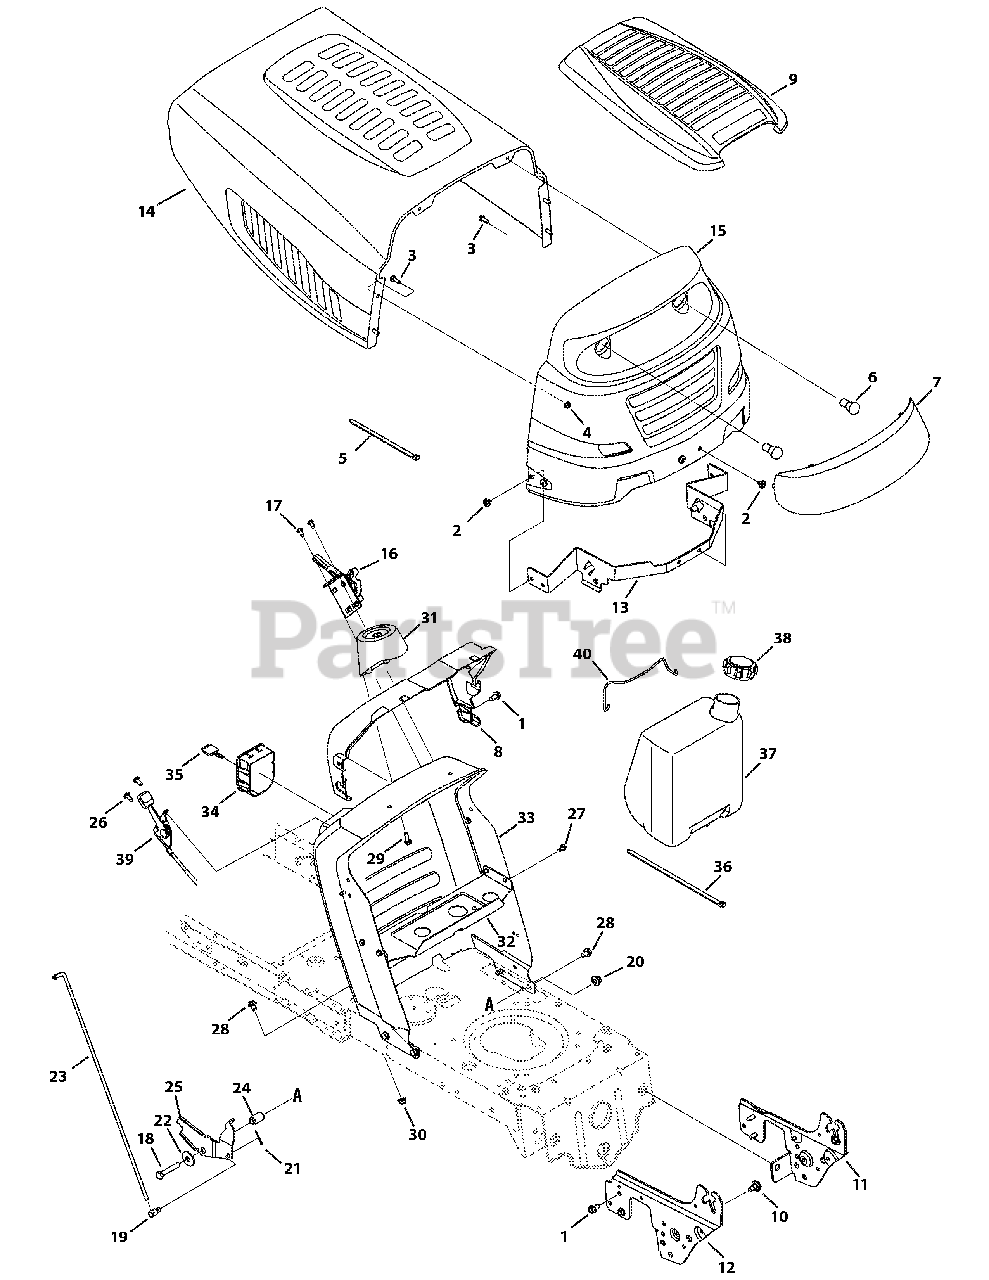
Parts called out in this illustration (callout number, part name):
1	Screw 5/16-18 x .750
2	Screw 5/16-18 x .375
3	Hex Screw 1/4-20 x .620
4	Flanglock Nut 1/4-20
5	Cable Tie
6	Miniature lamp 12V socket
7	Grill Lens
8	Dash
9	Hood cover
10	Shoulder Screw .43 x .29
11	Suppport Bracket LH
12	Suppport Bracket RH
13	Hood pivot bracket
14	Hood-Black
14	Hood-Gray
15	Grille-Black
15	Grille-Gray
16	Hydro Assembly
17	Screw 1/4-20 x .500
18	Hex Screw 3/8-16 x 2.00
19	Ferrule Adjust
20	Flang lock Nut 3/8-16
21	Cotter Pin
22	Flat Washer .411 x 1.25 x .100
23	Control Rod, Speed Selector
24	Flang Spacer .390 x .671 x 1.095
26	Screw 1/4-20 x .500
27	Hex Screw Washer 1/4-20 x .500
28	Screw 5/16-18 x .625
29	Hex Screw 1/4-15 x .750
30	Flanglock Nut 5/16-18
31	Support Shaft
32	Gas Tank Support Shaft
33	Dash RMC
34	Key Switch Module
35	Key
36	Cable Tie
37	Fuel Tank, 1.5 Gallons
38	Fuel Cap
39	Throttle/Choke Control Cable
